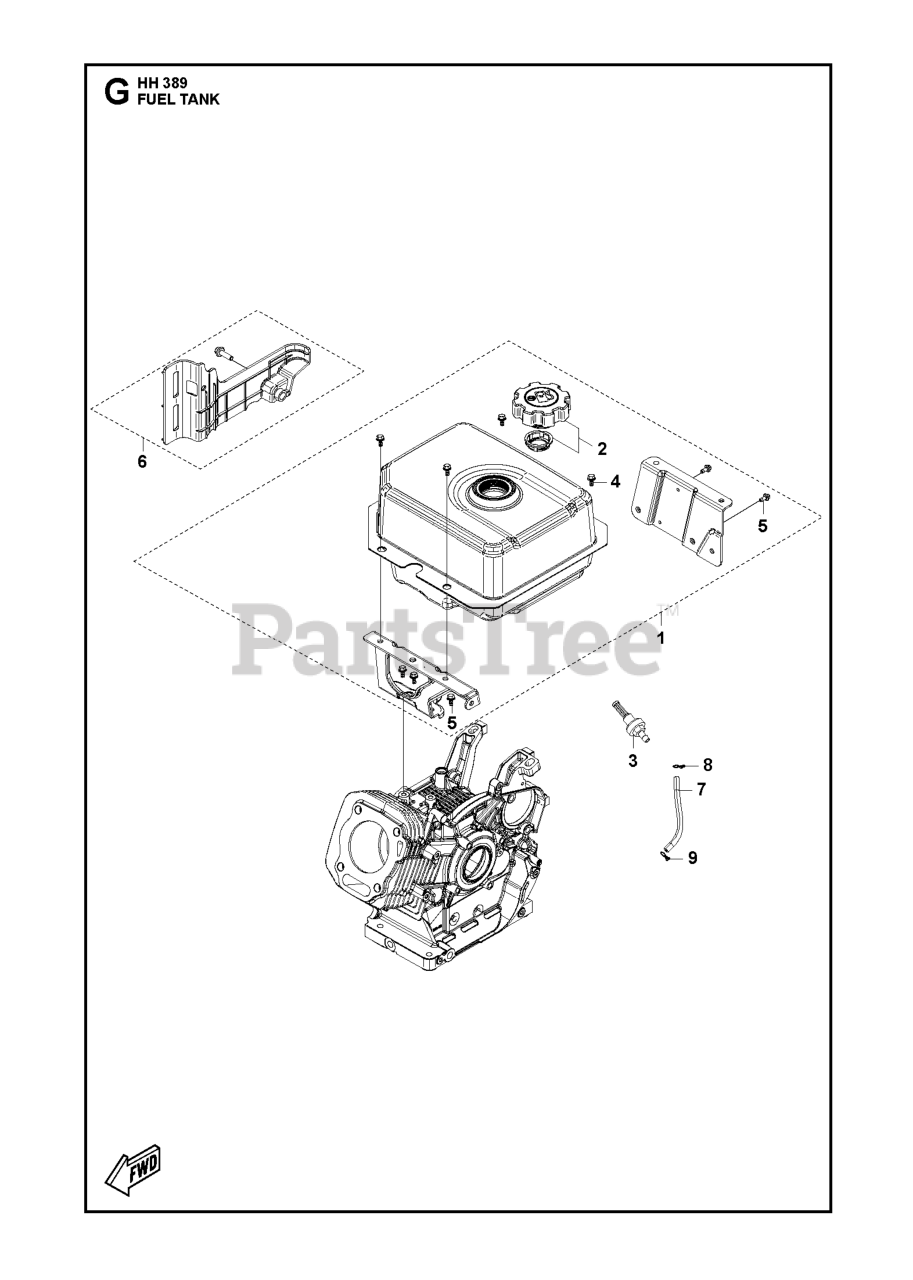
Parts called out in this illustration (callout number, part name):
1	FUEL TANK ASSY
2	FUEL CAP ASSY
3	FUEL GAUGE
4	BOLT
5	BOLT
6	COVER KIT FUEL TANK COVER
8	CLIP HOSE CLIP
9	CLIP HOSE CLIP
